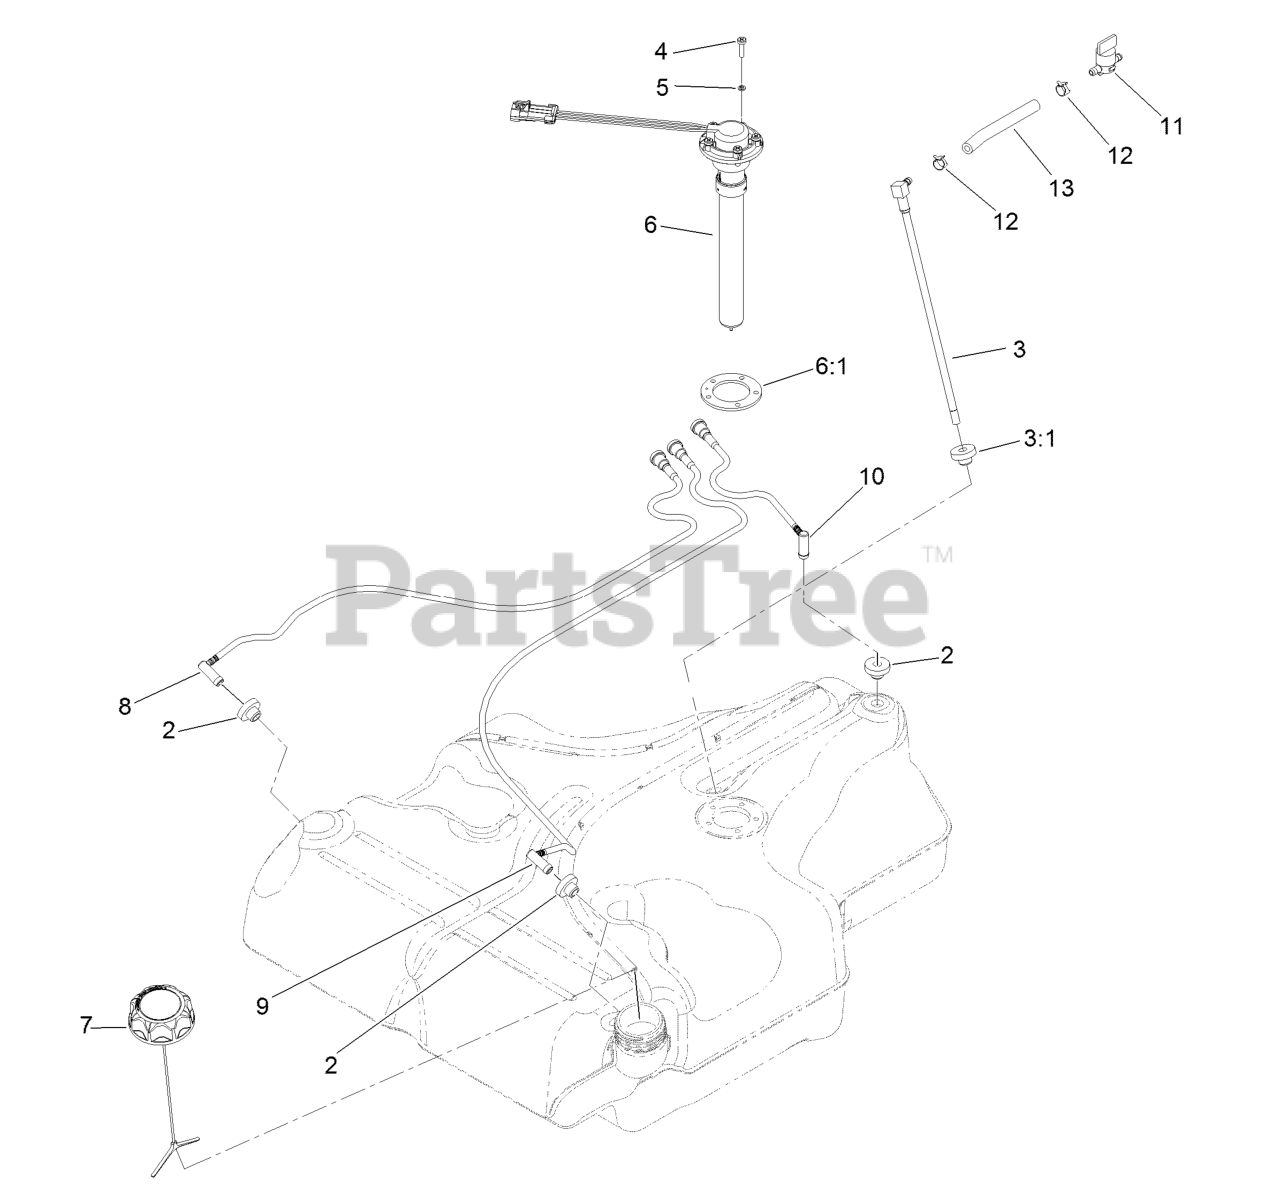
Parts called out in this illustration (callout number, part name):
2	BUSHING
3	FUEL LINE KIT (WITH GROMMET)
3:1	BUSHING
4	SCREW-PAN
5	WASHER-LOCK
6:1	GASKET-SENDER, FUEL
8	RH VENT LINE KIT (WITH GROMMET)
9	LH VENT LINE KIT (WITH GROMMET)
10	REAR VENT LINE KIT (WITH GROMMET)
11	VALVE-FUEL
12	CLAMP-HOSE
13	HOSE-FUEL
